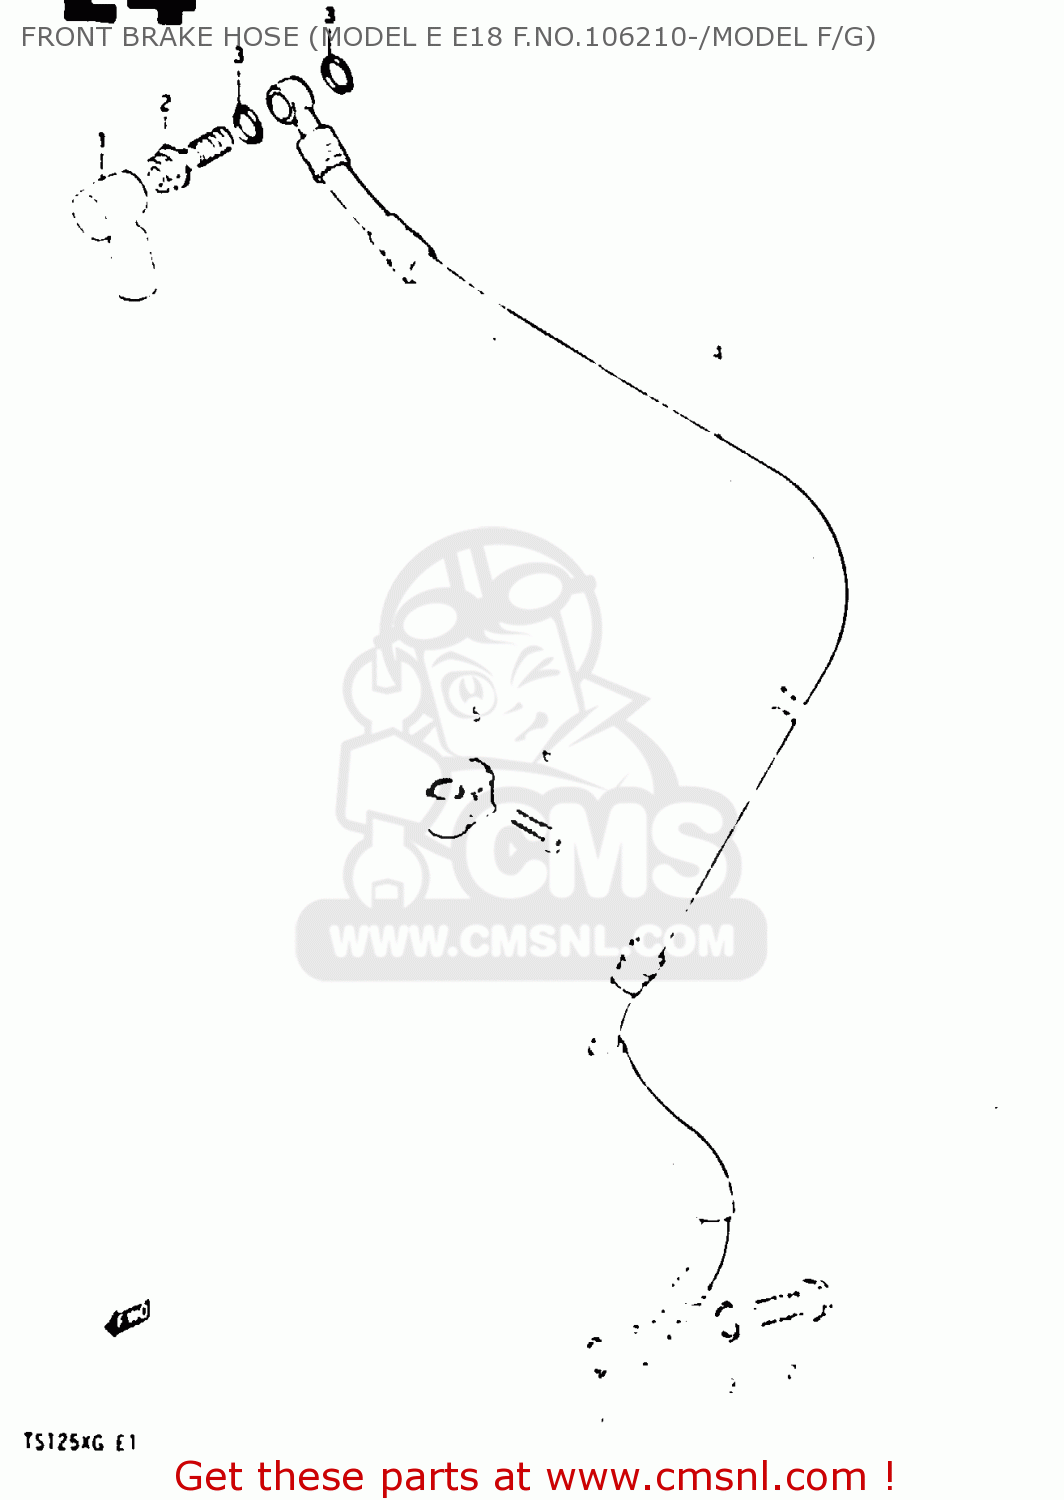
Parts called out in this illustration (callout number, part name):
1	BOOT,MASTER CYLINDER
2	BOLT UNION
3	WASHER(10X15X1.5)
4	HOSE, FRONT BRAKE
5	CLAMP,BRAKE HOSE
6	SCREW
